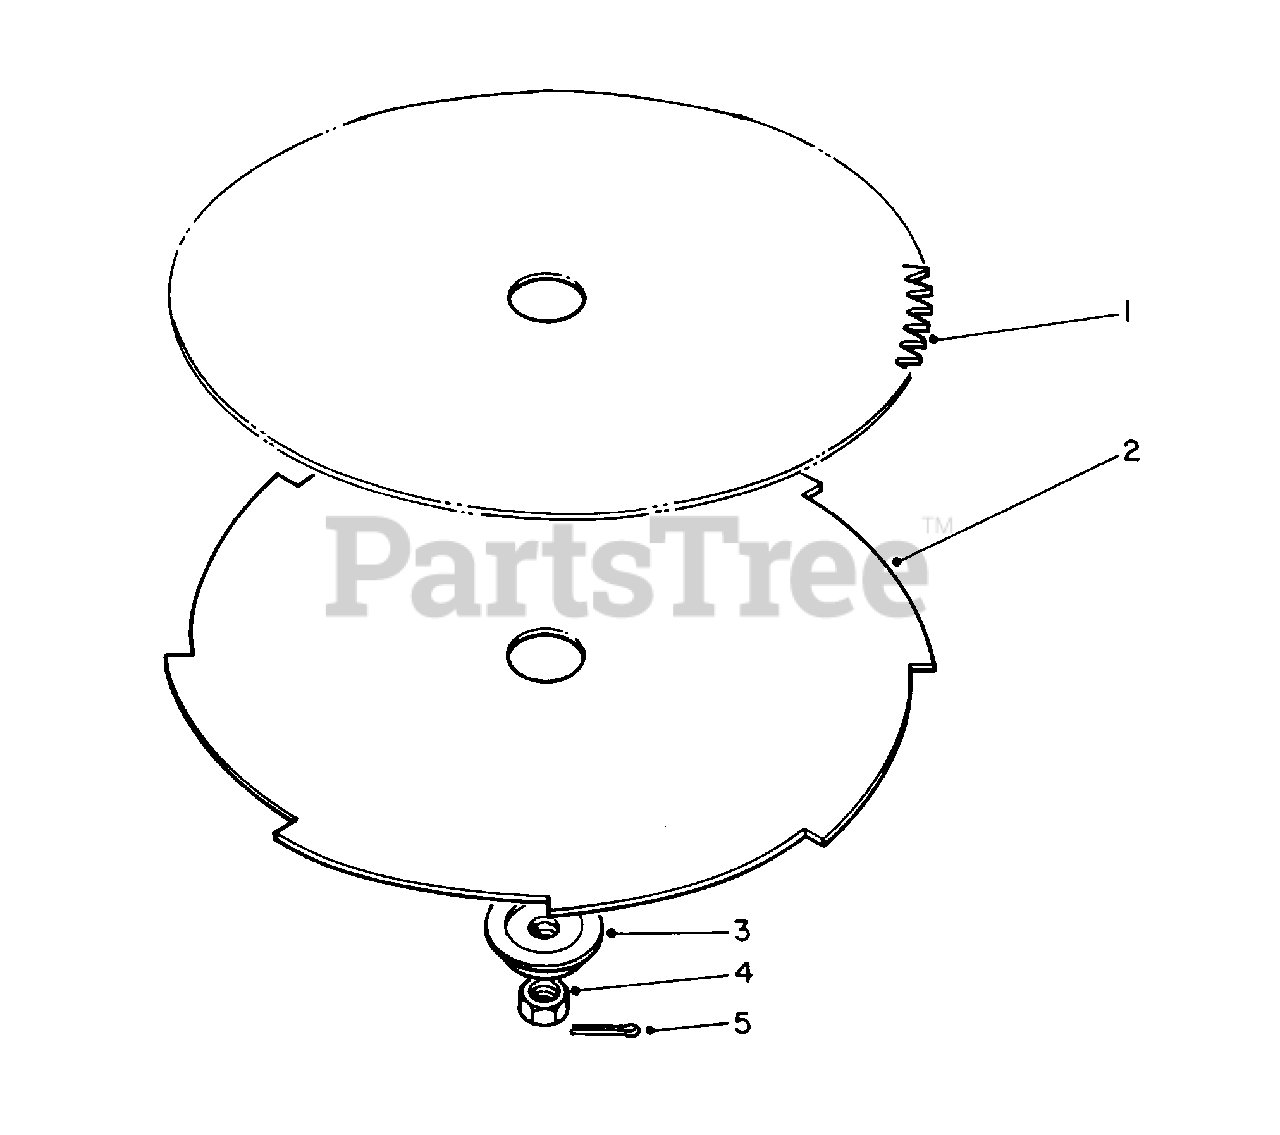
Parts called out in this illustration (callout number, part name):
1	8" Dia. Blade (80 Tooth)
2	8" Dia. Blade (8 Tooth)
3	Adapter-Blade
5	Pin Cotter
